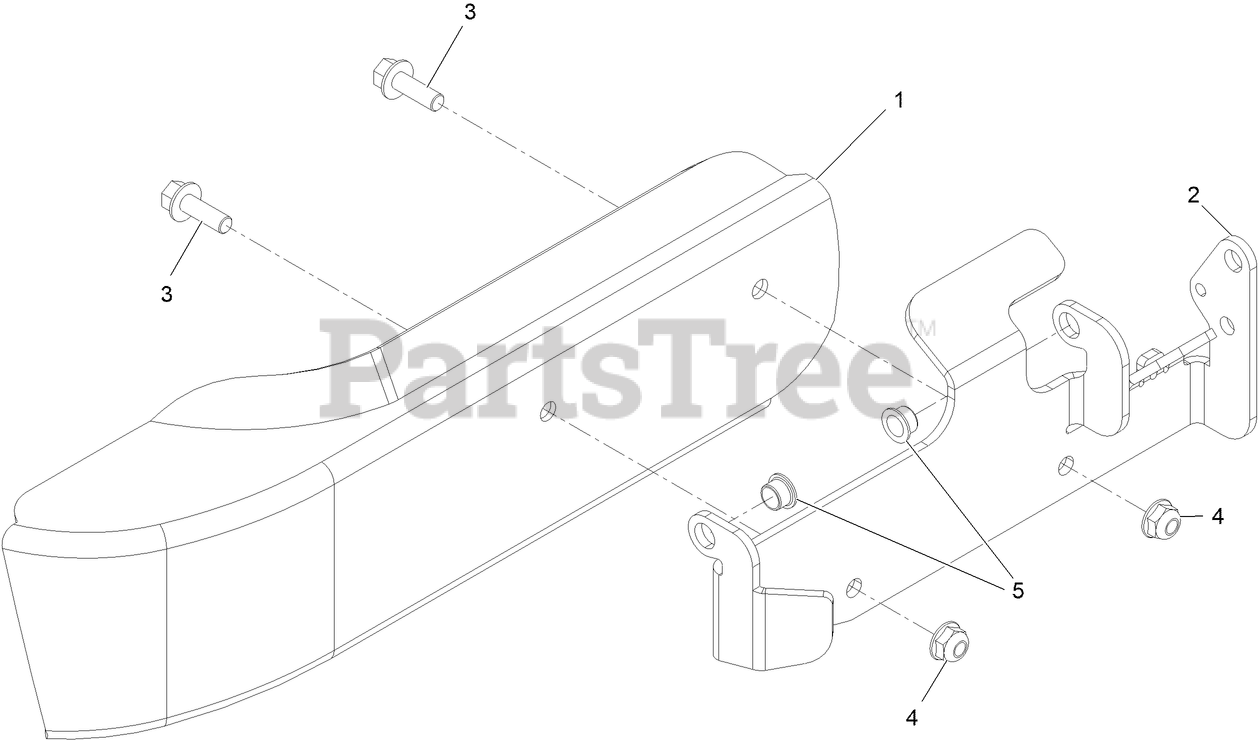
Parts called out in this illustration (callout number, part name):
1	CHUTE-DEFLECTOR
2	BRACKET-DEFLECTOR, SIDE
3	Screw-HHF
4	Nut-Hex Flange
5	BUSHING-FLANGE
